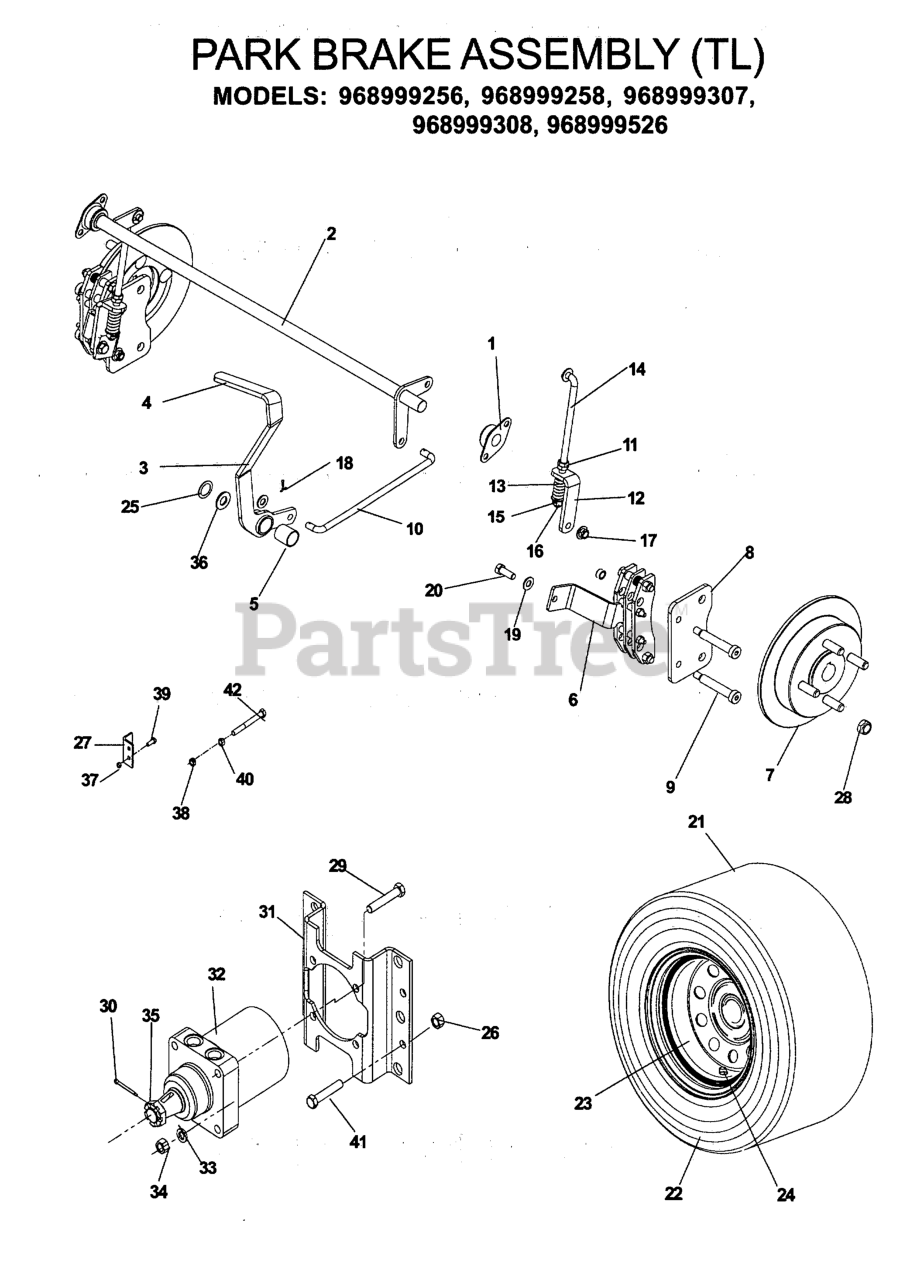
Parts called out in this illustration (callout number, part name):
1	FLANGE BEARING
2	BRAKE CROSS SHAFT
3	BRAKE LEVER WLDMT
4	GRIP, PARK BRAKE
6	CALIPER ASSEMBLY
8	PLATE, BRAKE
9	SB 3/8-16 X 2-1-1/2 SKT HDD ZD
10	LINKAGE, BRAKE
11	NUT 3/8-24 JAM
12	BRACKET, L
14	LINKAGE, REAR BRAKE
15	WASHER 3/8 SAE FLAT
16	NUT 3/8F CENTERLOCK
17	NUT HEX 3/8-16 NYLON, THIN
18	COTTER PIN 3/32 X 3/4
19	WASHER 3/8 SAE FLAT
20	HCS 3/8-16X1.GRD.5.ZD
21	WHEEL/TIRE.ASM.23X10.5-12.GREY
22	TIRE.TURF.MASTER.23X10.5-12
23	RIM 0 OFFSET 8.5" WIDE
24	VALVE STEM TR-412
25	RETAINING RING, 7/8"
26	NUT 1/2-13 HEX NYLOC ZD
28	LUG NUT 1/2F
29	HCS 1/2C X 2 3/4
30	PIN COTTER 4MM X 45MM
31	MOTOR STANDOFF
32	TL15 WHEEL MOTOR
33	WASHER 1/2" SPLIT LOCK
34	NUT HEX 1/2
35	NUT 3/4-16 HEX SLTD GR5 ZD
36	BSHG .875 X 1.375 X .074 ZD
37	NUT.1/4-20.HEX.NYLOC.ZD
38	NUT 3/8-16 NYLOC
39	HCS 1/4C X 3/4 HCS
40	NUT 3/8C WHIZ
41	HCS 1/2C X 1 1/4 SERRATED HEAD
42	HCS 3/8C X 2 1/2
